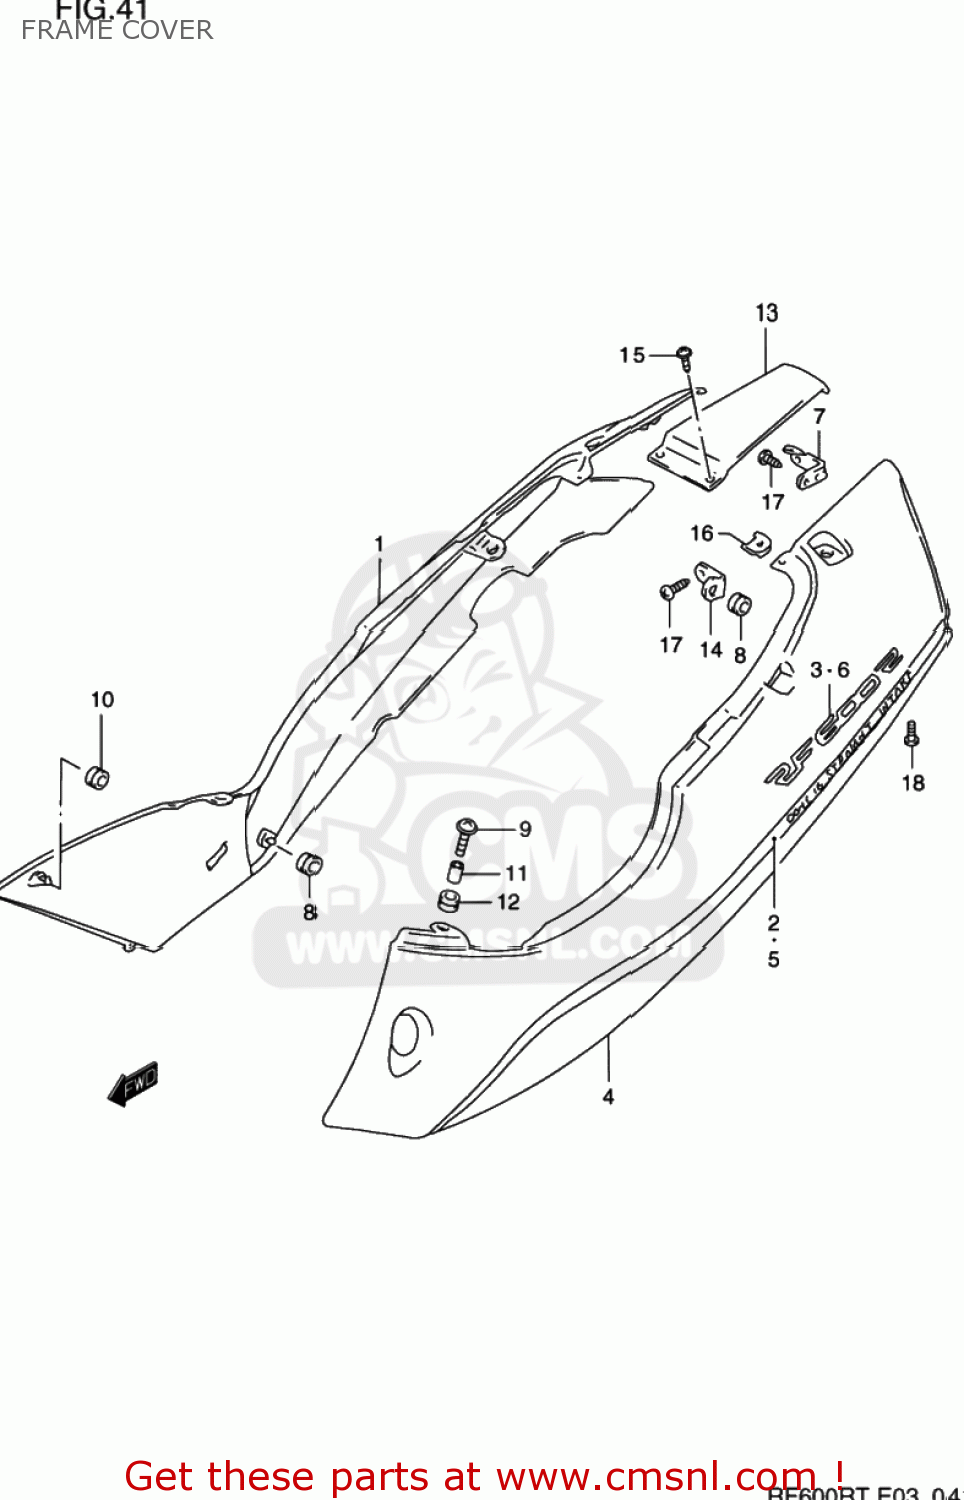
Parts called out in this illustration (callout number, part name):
1	COVER ASSEMBLY,FRAME,RIGHT
2	TAPE SET,FRAME COVER S
3	EMBLEM,FRAME COVER
4	COVER ASSEMBLY,FRAME,LEFT
5	TAPE SET,FRAME COVER S
6	EMBLEM,FRAME COVER
7	BRACKET,FRAME COVER,R
8	CUSHION
9	SCREW
10	CUSHION,FRAME COVER FR
11	SPACER
12	CUSHION
13	COVER,FRAME CTR
14	BRACKET,RR COMBINATION LAMP
15	SCREW 5X12
16	NUT
17	SCREW
18	SCREW 5X12
